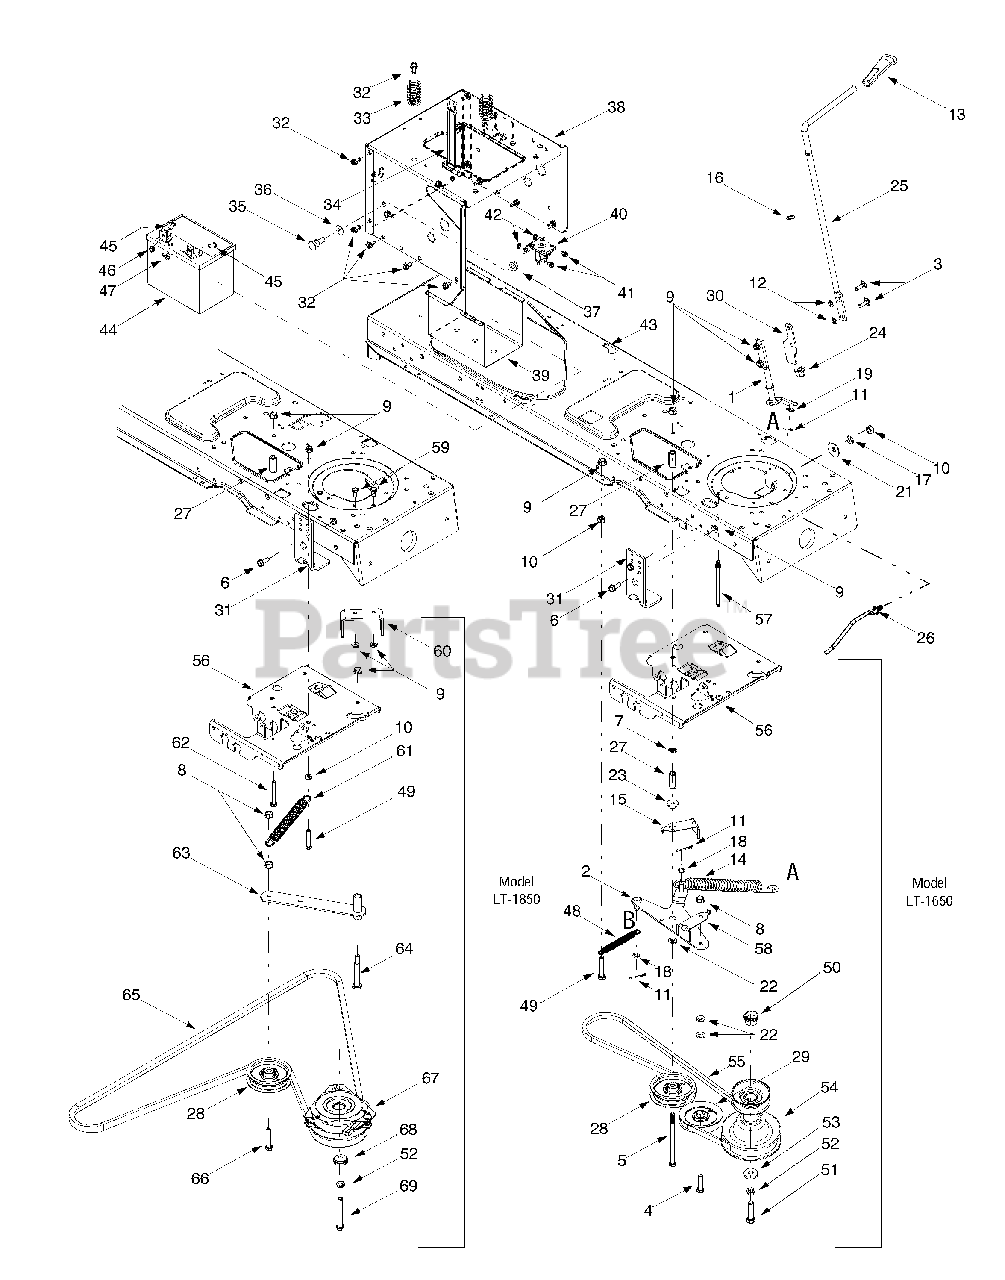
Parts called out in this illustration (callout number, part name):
1	PTO Engage Lever Assembly
4	Hex Cap Screw, 3/8-16 x 1.5
5	Hex Cap Screw, 3/8-16 x 5.5
6	Hex Head Washer Screw, 5/16-18 x .875
7	Push Nut, 3/8
8	Flange Lock Nut, 3/8-16
9	Flange Lock Nut, 5/16-18
10	Hex Nut, 5/16-18
11	Cotter Pin, 1/8 x 1.25
12	Speed Nut, .3125
13	PTO Knob
14	Extension Spring, .75 x 6.75
16	Flat Washer, .510 x .750 x .033
17	Lock Washer, 5/16
18	Flat Washer, .385 x .62 x .063
19	Flat Washer, 5/16
20	Flat Washer, .406 x .875 x .059
21	Bell Washer, .39 x 1.13 x .062
22	Flat Washer, .407 x .812 x .135
23	Shoulder Spacer, .380
24	Hex Split Flange Bearing, .5
26	Belt Keeper Rod
27	Spacer, 3/8 x 1.54
28	Idler Pulley, 3.5
29	Idler Pulley, 4.0
32	Self Tapping Screw, 5/16-18 x .625
33	Compression Spring, 1.28 x 3.5
34	Battery Strap
35	Shoulder Screw, .625 x .5, 7/16-20
36	Bell Washer, .45 x 1.0 x .062
37	Flange Lock Nut, 7/16-20
41	Self Tapping Screw, 1/4-20 x .5
42	Lock Washer, 1/4
45	Hex Cap Screw, 1/4-20 x .62
46	Hex Sems Nut, 1/4-20
47	Wing Nut, 1/4-20
48	Extension Spring, .50 x 5.0
49	Hex Cap Screw, 5/16-18 x 1.75
51	Hex Head Cap Screw, 7/16-20 x 1.25
52	Lock Washer, 7/16
53	Flat Washer, .450 x 1.25
54	Engine Pulley, 3.56 OD x 5.56
55	PTO Belt
57	Keeper Pin, 5/16 x 4.75
58	Belt Guard
59	Hex Cap Screw, 5/16-18 x .625
62	Hex Cap Screw, 3/8-16 x 2.5
65	PTO Belt (LT-1850)
66	Hex Cap Screw, 3/8-16 x 2.0
67	Electric PTO Clutch
68	Shoulder Spacer, 1.38 x .445 x .36
69	Hex Cap Screw, 7/16-20 x 3.25 (Grade 5)
